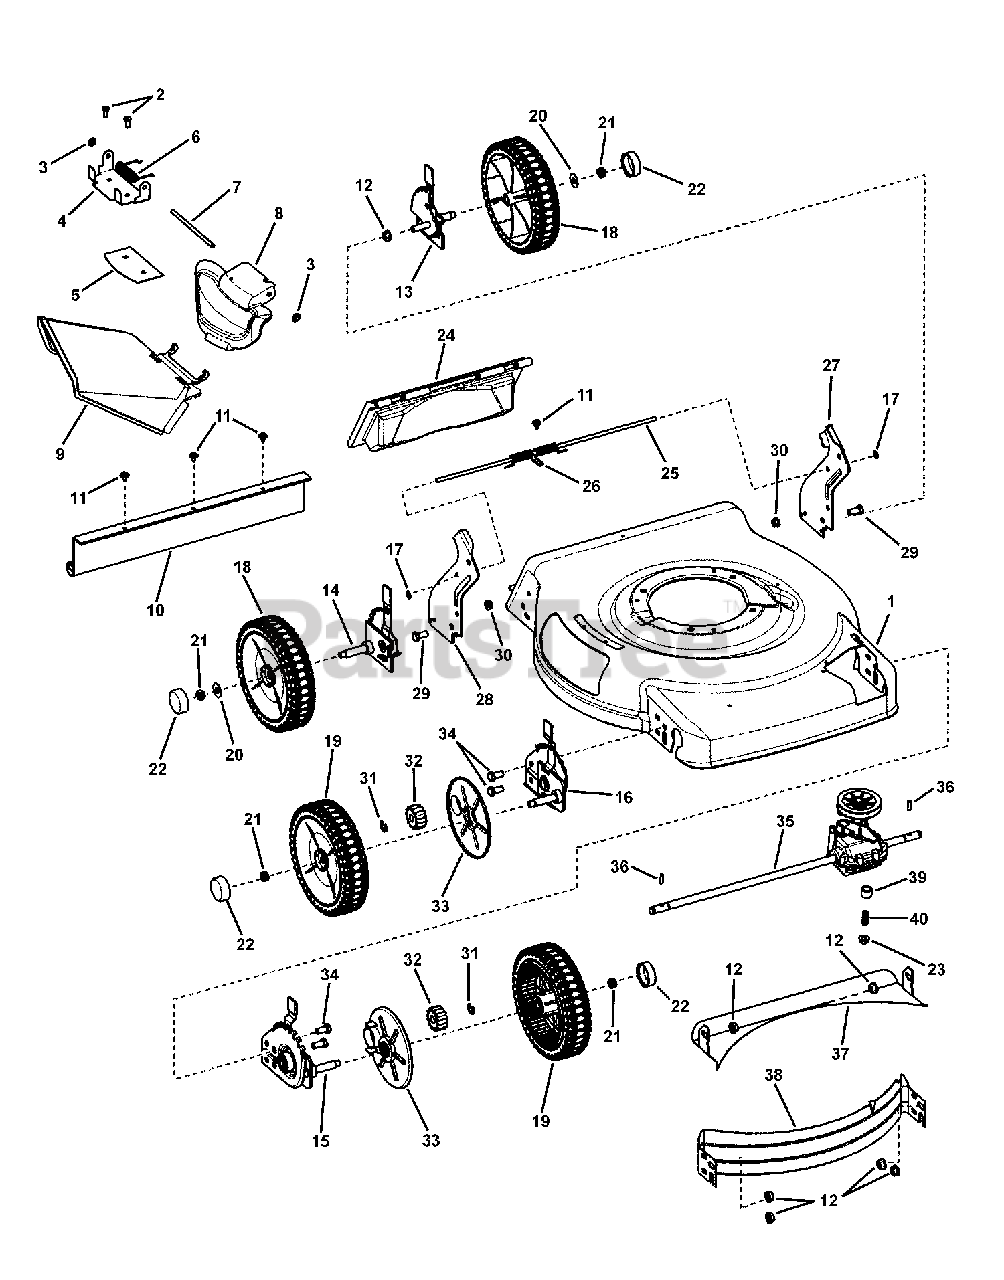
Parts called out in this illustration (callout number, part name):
1	DECK, 22" Walk, 3-N-1
2	SCREW, 1/4-20 x 11/16" Pan Head Self-Tap - Torx
3	PUSHNUT, 1/4"
4	BRACKET, Chute
5	PLATE, Mulch, 22" RB Scott's
6	SPRING, Chute - Torsion
7	ROD, Chute Pivot - 1/4" Dia. x 5.55"
8	COVER, Mulch, Plastic, Black
9	SIDE CHUTE, Plastic, Black
10	GUARD, Rear
11	SCREW, #10-24 x 1/2" Hex Washer Self-Tap - Sems
12	NUT, 3/8-16 Hex Flange Lock, GR 5
13	ASSY, Height-of-Cut, Left Rear, 7 Position
14	ASSY, Height-of-Cut, Right Rear, 7 Position
15	ASSY, Height-of-Cut, Left Front, 22" WBM, Self-Prop, 7 Position
16	ASSY, Height-of-Cut, Right Front, 22" WBM, Self-Prop, 7 Position
17	CAP, Retainer
18	ASSY, Wheel, 8" x 2" Idle, NB Murray Tread, Gray
19	ASSY, Wheel, 8" x 2" Drive, NB, Murray Tread, Gray
20	WASHER, 1" O.D. x .387 I.D. Flat
21	NUT, 3/8-16 Hex Center Lock, YZ
22	HUBCAP, Round, Black
23	NUT, 5/16-18 Hex Flange Lock
24	DOOR, Rear Discharge, 22" Walk Mower
25	ROD, Pivot, Rear Door - 1/4" Dia. X 17-1/2"
26	SPRING, Torsion, Rear Door, 22" Walk Mower
27	BRACKET, Lower Handle, RH
28	BRACKET, Lower Handle, LH
29	BOLT, 5/16-18 x 5/8" Hex Flange Lock, YZ
30	NUT, 5/16-18 Flange Lock, YZ
31	RING, External Retaining
32	GEAR, Pinion, 22" WBM, FWD
33	SHIELD, Dust, 22" WBM, FWD
34	SCREW, 3/8-16 x 3/4" Hex Head Cap, GR 5
35	TRANSMISSION, 22" WBM Single Speed, Front Wheel Drive
36	DRIVE PIN, 22" WBM, Front Wheel Drive
37	BAFFLE, Rear, 22" Deck
38	BAFFLE, Front, 22" WBM
39	SPACER, Engine
40	SPRING, Compression
